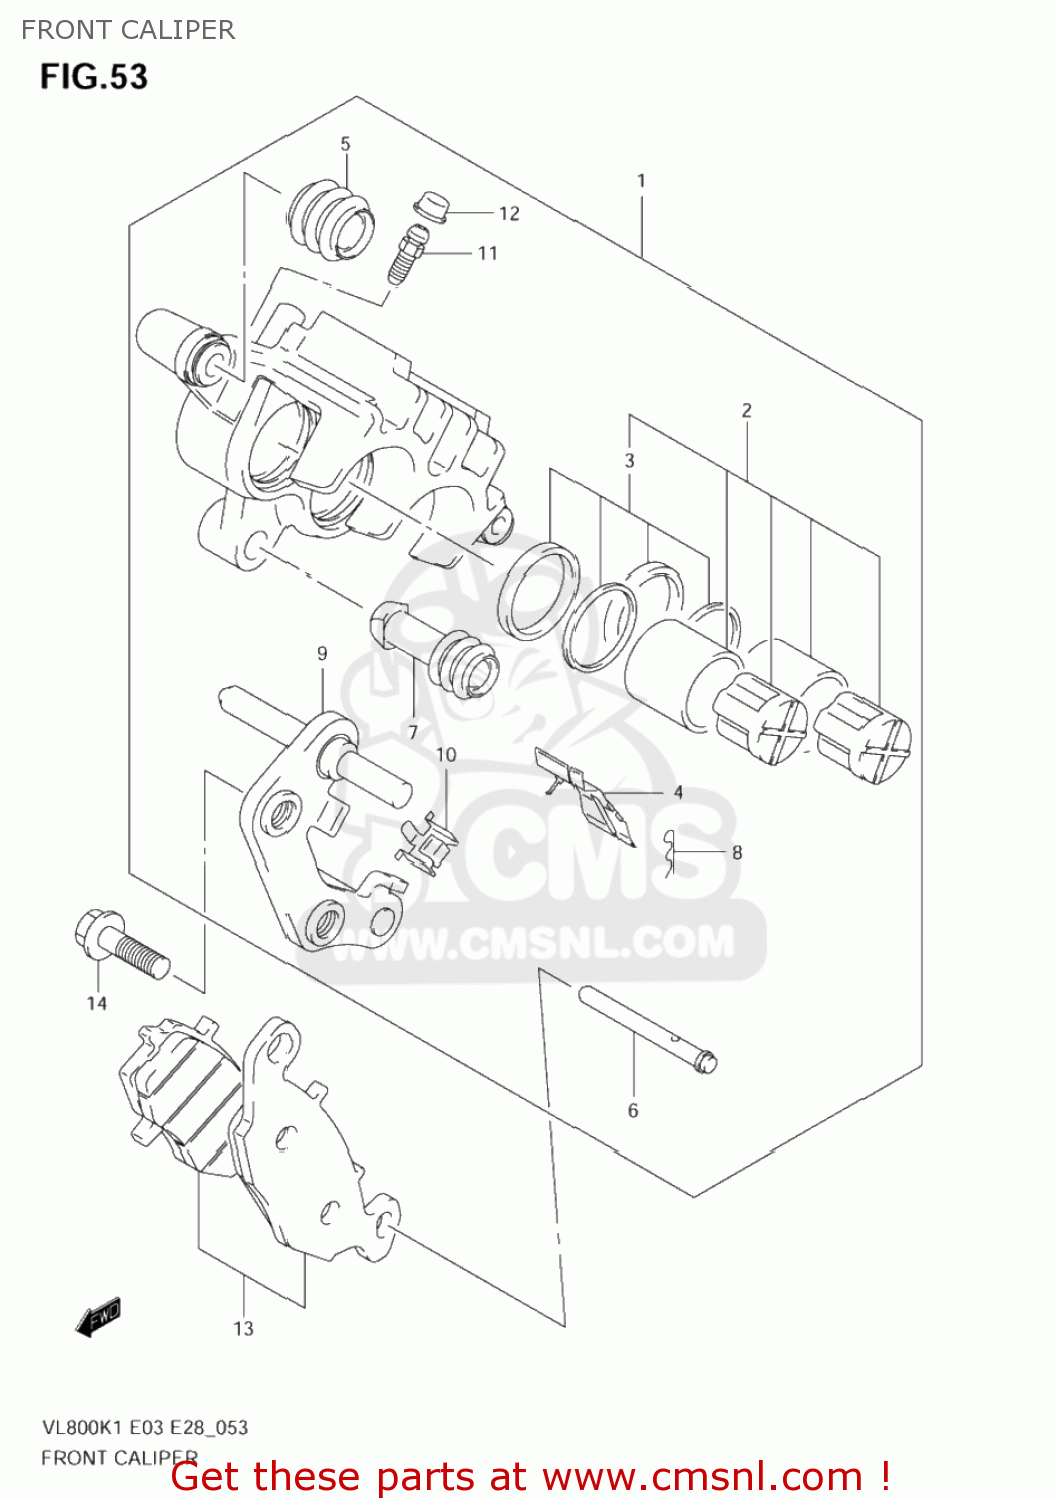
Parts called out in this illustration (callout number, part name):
1	CALIPER ASSY,FR
2	PISTON SET
3	SEAL SET,PISTON
4	SPRING,PAD,R
5	BOOT,AXLE
6	PIN,PAD
7	INSULATOR,AXLE
8	CLIP,PAD PIN
9	CARRIER,CALIPER,R
10	GUIDE,PAD
11	BLEEDER
12	CAP,BLEEDER PLUG
13	PAD SET (NAS)
14	BOLT
